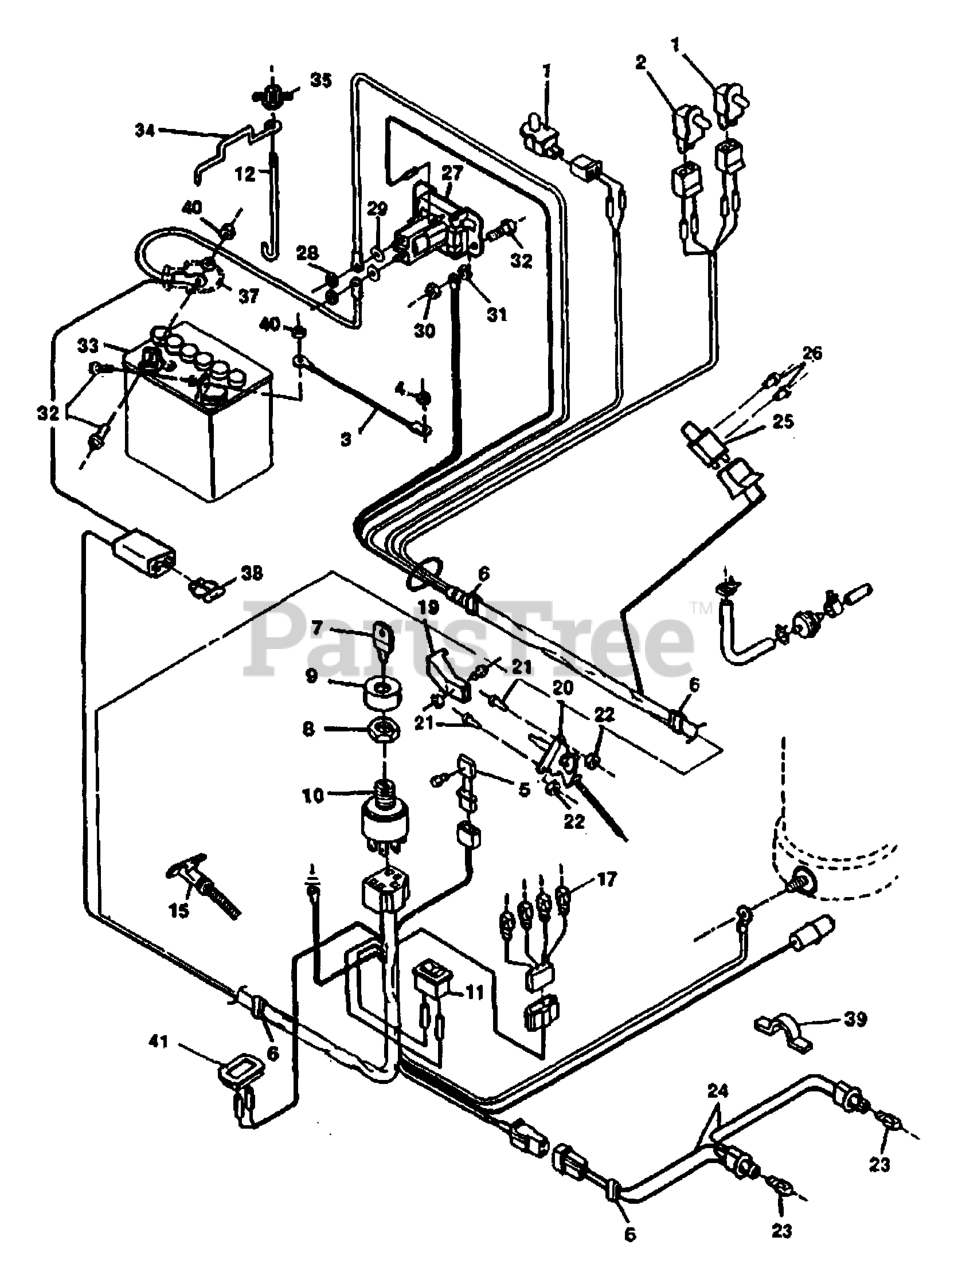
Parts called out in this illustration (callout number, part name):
1	SWITCH, SEAT
2	SWITCH
4	NUT 5/16X18
6	TIE,CABLE
7	KEY SET
8	NUT
9	DUST PROTECTION
15	CHOKE CONTROL
20	THROTTLE CONTROL
21	SCREW
22	NUT
26	SCREW12X1/2ä
28	NUT
29	LOCK WASHER
30	NUT
31	NUT
